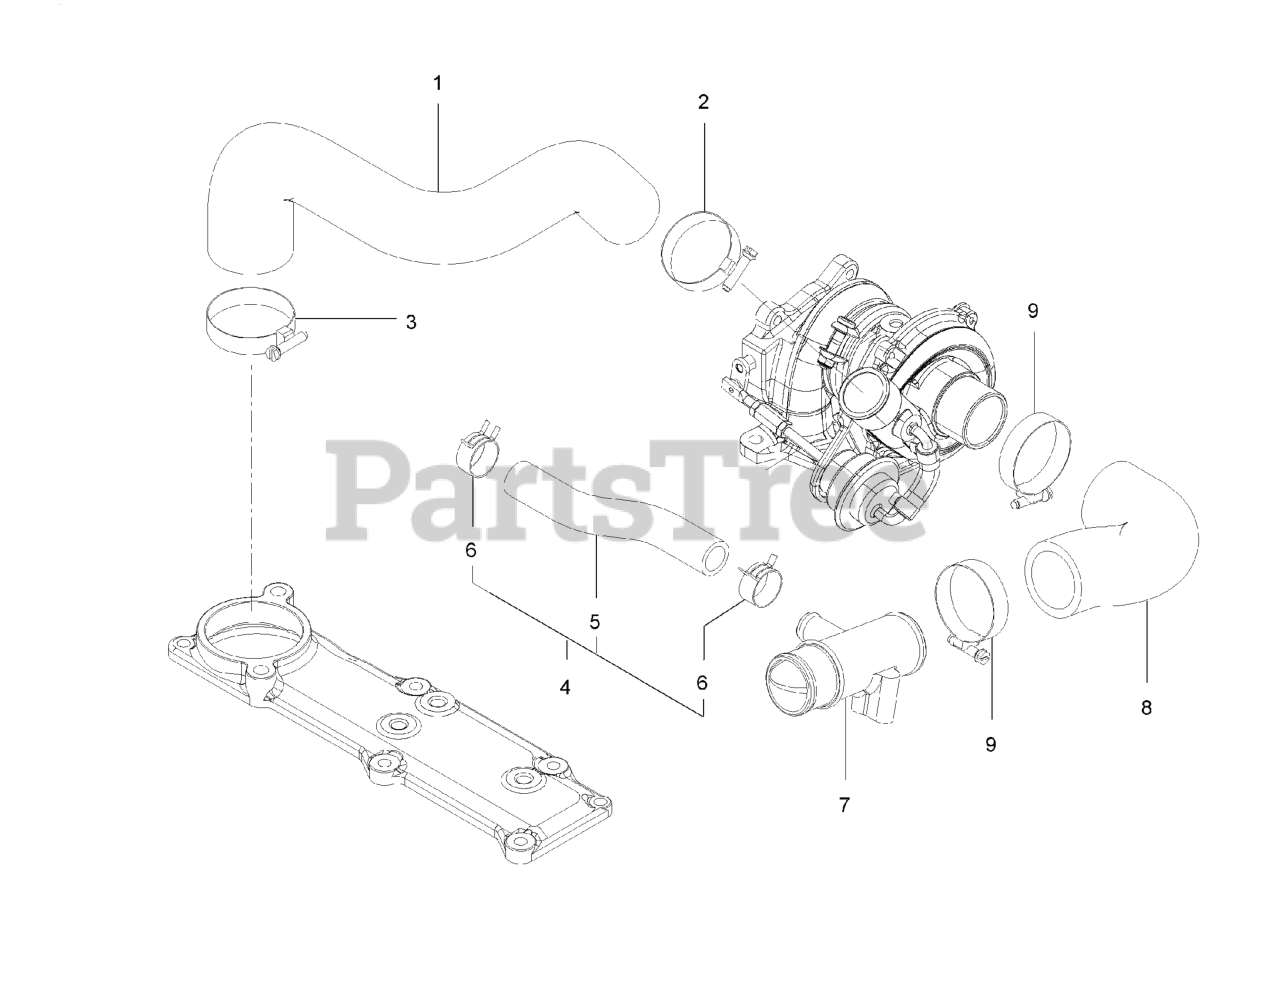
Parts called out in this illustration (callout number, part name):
1	HOSE-AIR INTAKE
2	CLAMP-HOSE
3	CLAMP-HOSE
4	HOSE ASM-BREATHER
5	Hose-Breather
6	CLIP-HOSE
7	JOINT-BREATHER
8	HOSE-AIR INTAKE
9	CLAMP-HOSE
